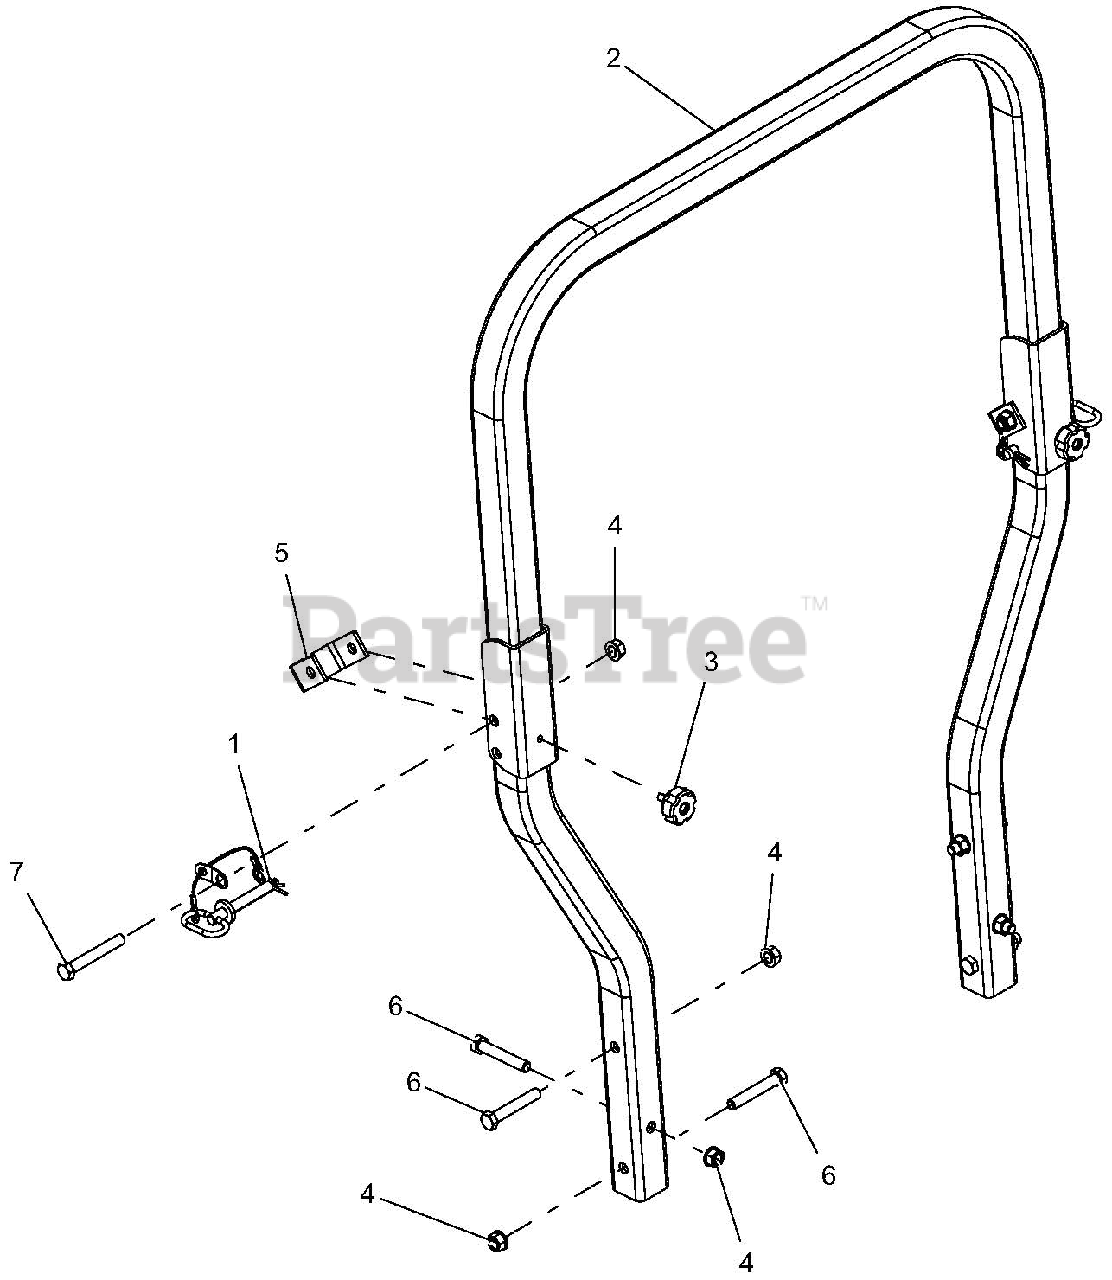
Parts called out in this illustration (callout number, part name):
1	ASSY, ROPS PIN/LANYARD
2	ROPS INCLUDES HOOP RH AND LH SUPPORT
3	KNOB, ROUND 5/16-18 X .750
4	NUT, LK-TOP-FLG .50-13 YWZC
5	BRKT, ROPS STOP
6	BLT-HEX .50-13X3.00 GR5 YWZC
7	BLT-HEX .50-13X3.50 GR5 YWZC
